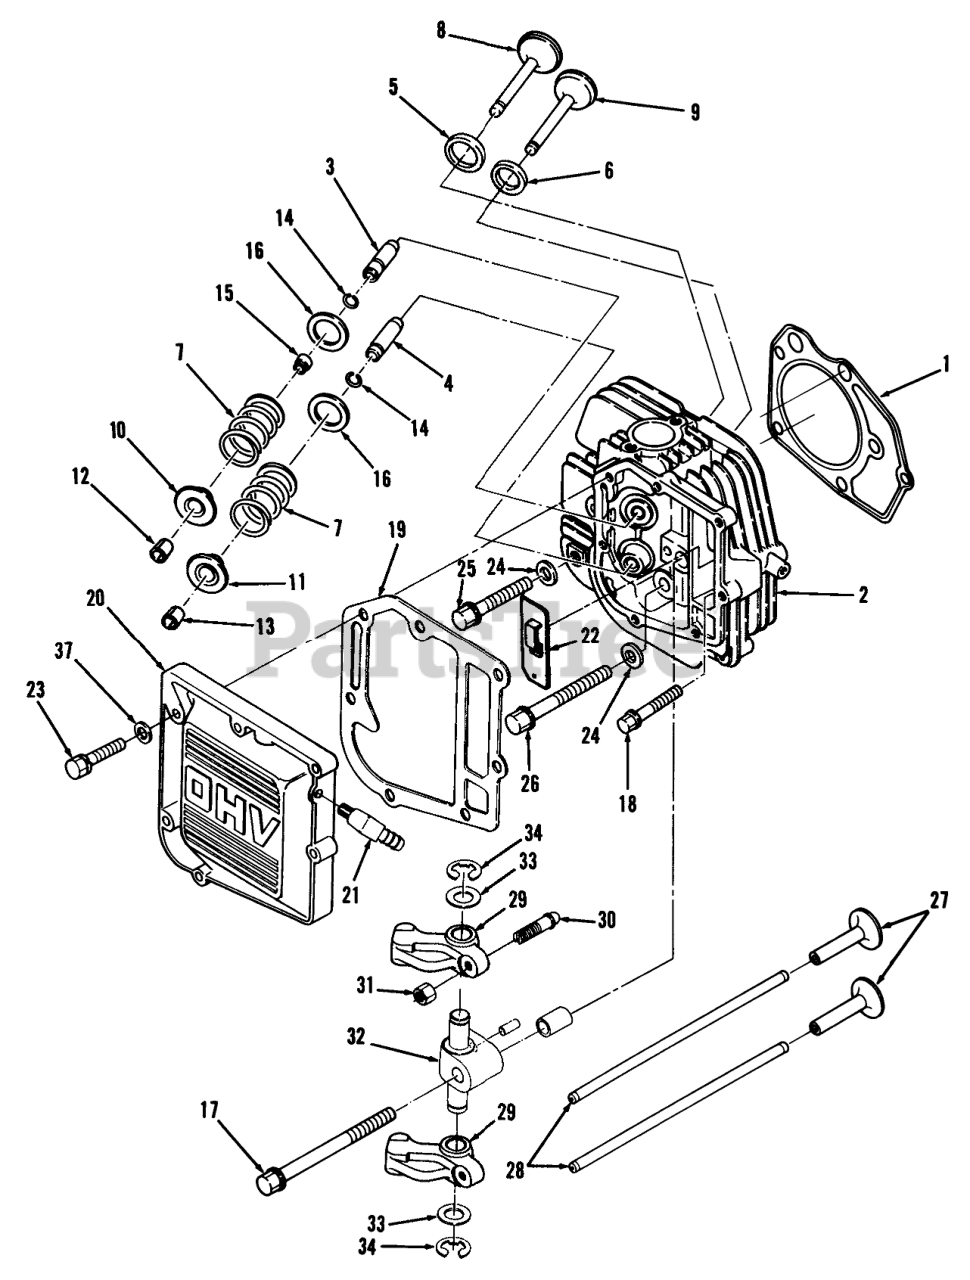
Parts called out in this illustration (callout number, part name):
1	GSKT-CYL HEAD
2	Cylinder Head Assembly (Incl. Ref. #3-16)
3	GUIDE-INTAKE VALVE
4	GUIDE-EXH VALVE
5	Seat-Intake Valve
6	Seat-Exhaust Valve
7	SPRING-VALVE
8	VALVE-INTAKE MKD IN
9	VALVE-EXHAUST MKD EX
10	RETAINER-VLV SPG IN
11	ELBOW-90 DEGREES
12	Lock-Intake
13	LOCK-VALVE EXHAUST
14	RING-VALVE GUIDE
15	Seal-Intake
16	WASHER-VALVE SPRING
17	BLT-CYL HD M10X125MM
18	BLT-CYL HD M8X50MM
19	Seal
20	ASSEMBLY COVER
21	ELBOW-90 DEGREES
22	BREATHER
23	SCRW-CP SH M6X25MM
24	WASHER-FLAT M10
25	BLT-CYL HD M10X66MM
26	BLT-CYL HD M10X86MM
27	TAPPET
28	ROD-PUSH
29	Rocker Arm Assembly (Incl. Ref. #30 & 31)
30	SCRW-LASH ADJUSTING
31	NUT-LASH ADJUSTING
32	SHAFT-ROCKER ARM
33	Rocker Arm Washer
34	CLIP-RETAINER
35	PIN-DOWEL
36	PIN-DOWEL HOLLOW
37	WASHER-FLAT
